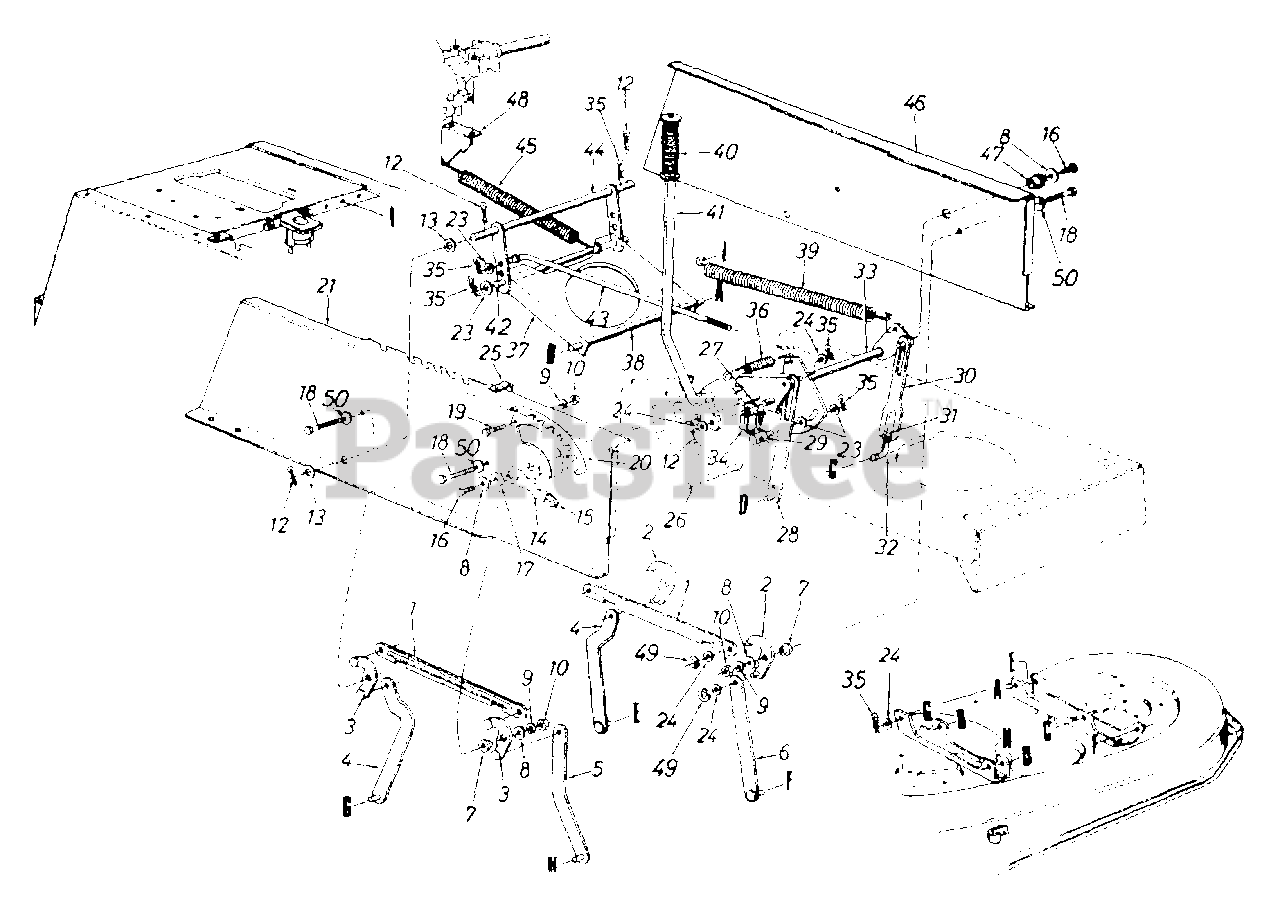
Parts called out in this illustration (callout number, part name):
3	Pivot Link Ass'y. - R.H.
7	Shld. Spacer .318" I.D.
8	Fl-Wash. .344" I.D. x 1.125" O.D.
9	L-Wash. 5/16" I.D.
10	Hex Nut 5/16-18 Thd. (Gr. 5)
12	Cotter Pin 1/8" Dia.
13	Fl-Wash. .635" I.D. x 1.0" O.D.
14	Hgt Adj. Stop Lever Ass'y.
15	Knob
16	Hex Wash. TT-Tap Scr. 5/16-18 x .75"
17	Flange Brg. .63" I.D.
18	Hex Wash. Hd. Scr. 5/16-18 x .875" Lg.
19	Hex Bolt 5/16-18 x .75" Lg.
20	Index Brkt.
24	Fl-Wash. .531" I.D. x .93" O.D.
25	Clamp
26	Running Board Rod
27	Hex Wash. Hd. Tap Scr.
31	Hex Nut 1/2-20 Thd. (Gr. 5)
32	Lift Link Adjuster
35	Inter. Cotter Pin 3/8" Dia.
36	Extension Spring
39	Extension Spring
40	Grip (Lift Handle)
43	Disengagement Rod
49	"E"-Ring
50	Bell-Wash. .325" I.D.
